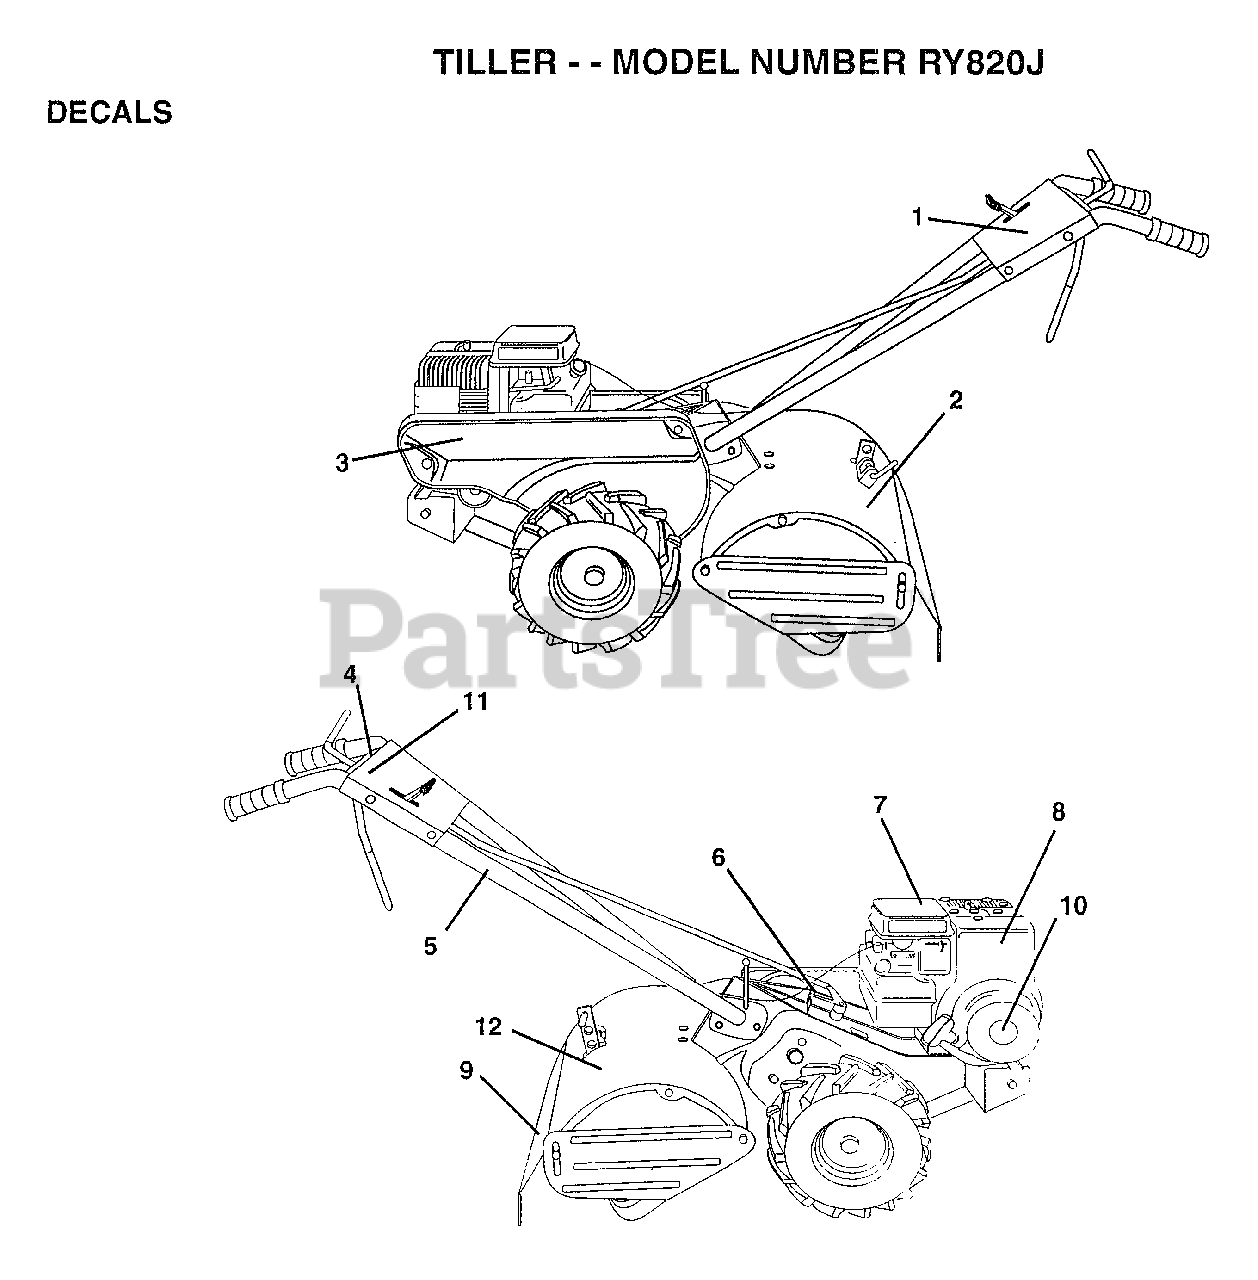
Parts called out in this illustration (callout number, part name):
3	DECAL, LOGO
5	DECAL TI
6	DECAL CRT
7	DECAL TI
8	DECAL, BRIGGS & STRATTON
11	DECAL REVERSE
12	DECAL.CAUTION
